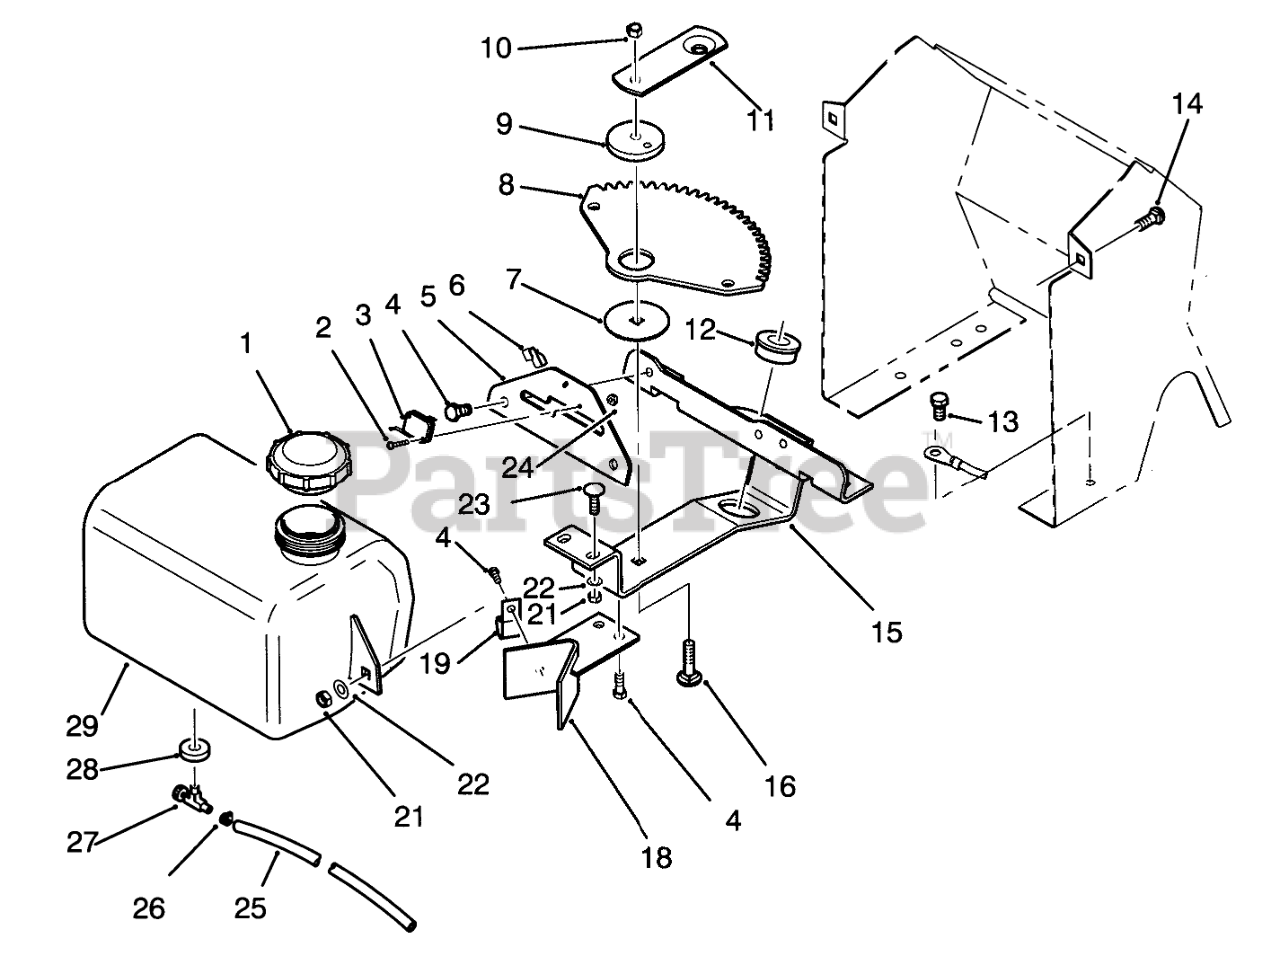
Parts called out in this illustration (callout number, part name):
1	CAP GAS
2	Screw
3	SWITCH - CLUTCH
4	Screw
5	PLATE SHIFT R
6	CLIP-CABLE
7	WASHER-BEARING
8	GEAR-SECTOR
9	BUSHING
11	Plate
12	BEARING-WHEEL
13	SCREW
14	SCREW-CARR
15	STEERING BRKT - W/A R
16	BOLT-CARR
18	Stop
19	CLIP
21	NUT-LOCK, NI
22	WASHER-PLAIN
23	Bolt-Carriage
24	NUT HEX 4-40 ELAST
25	HOSE - FUEL LINE
26	CLAMP-HOSE
27	VALVE-FUEL
28	BUSHING
29	Fuel Tank
